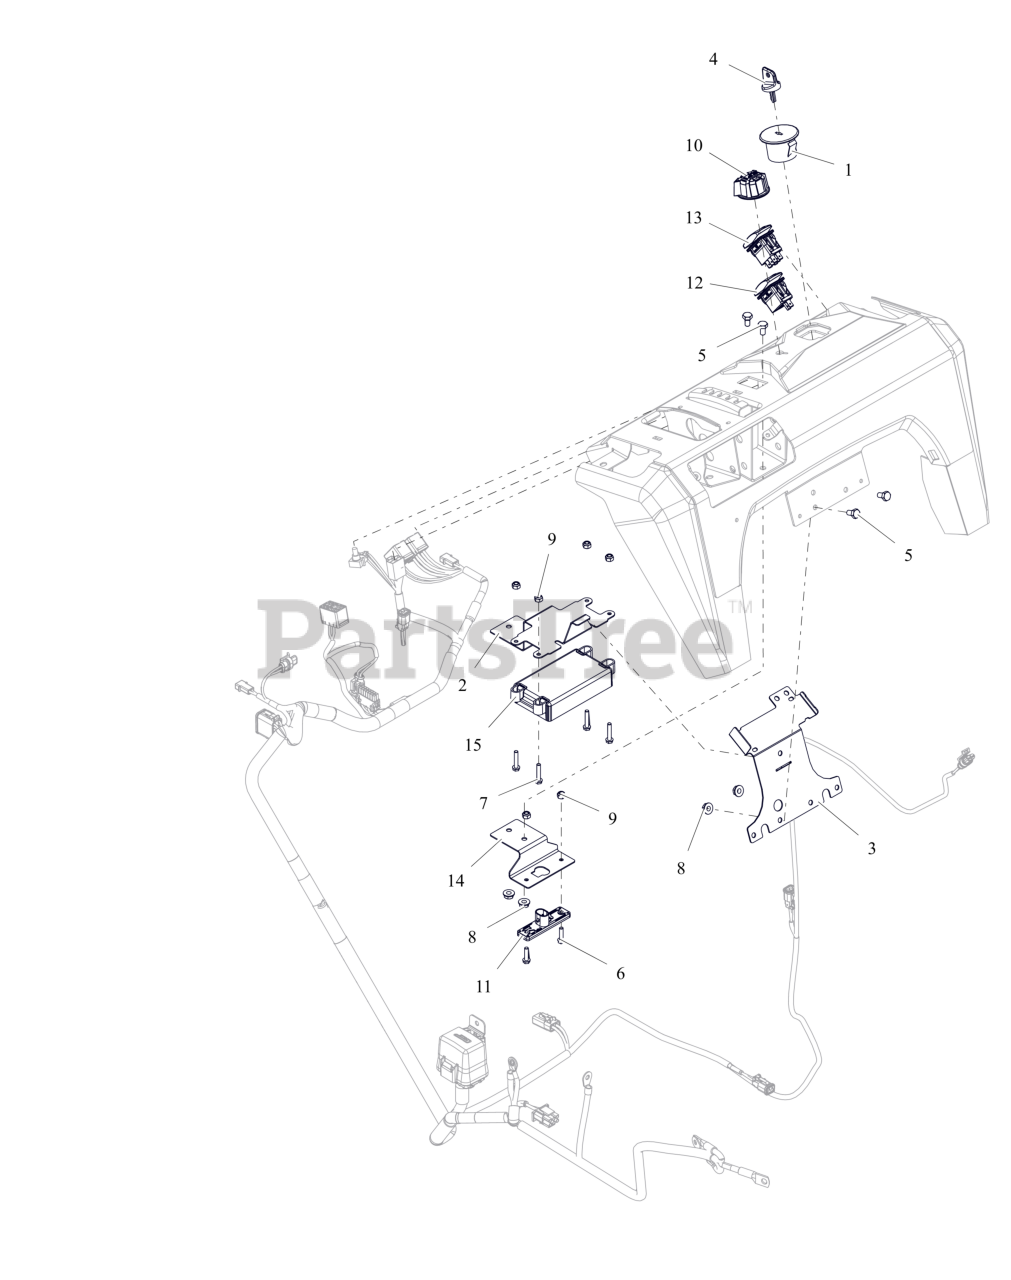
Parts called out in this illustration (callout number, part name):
1	KEYSWITCH-IGNITION 3 POS
2	BRACKET, ENGINE EFI-LCT LOWER
3	BRACKET, ENGINE EFI-LCT UPPER
4	KEY- IGNITION
5	BLT,HEX .25-20X.50 G5 ZCC
6	BLT, HWH #10-24X.75 ZCC
7	BLT, HWH #10-24X1.00 ZCC
8	NUT-LK-TOP-FLG .250-20 GF ZCC
9	NUT-LK-NYL #10-24 G2 ZCC
10	KNOB- CONTROL EFI
11	LIGHT- LED - 3BAR HEADLIGHT
12	SWITCH-ROCKER - SPST-ON/OFF
13	SWITCH-ROCKER - DPDT-ON/OFF/ON
14	BRKT- DASH UNDER LIGHT
15	ECU, AX420 12V EFI
